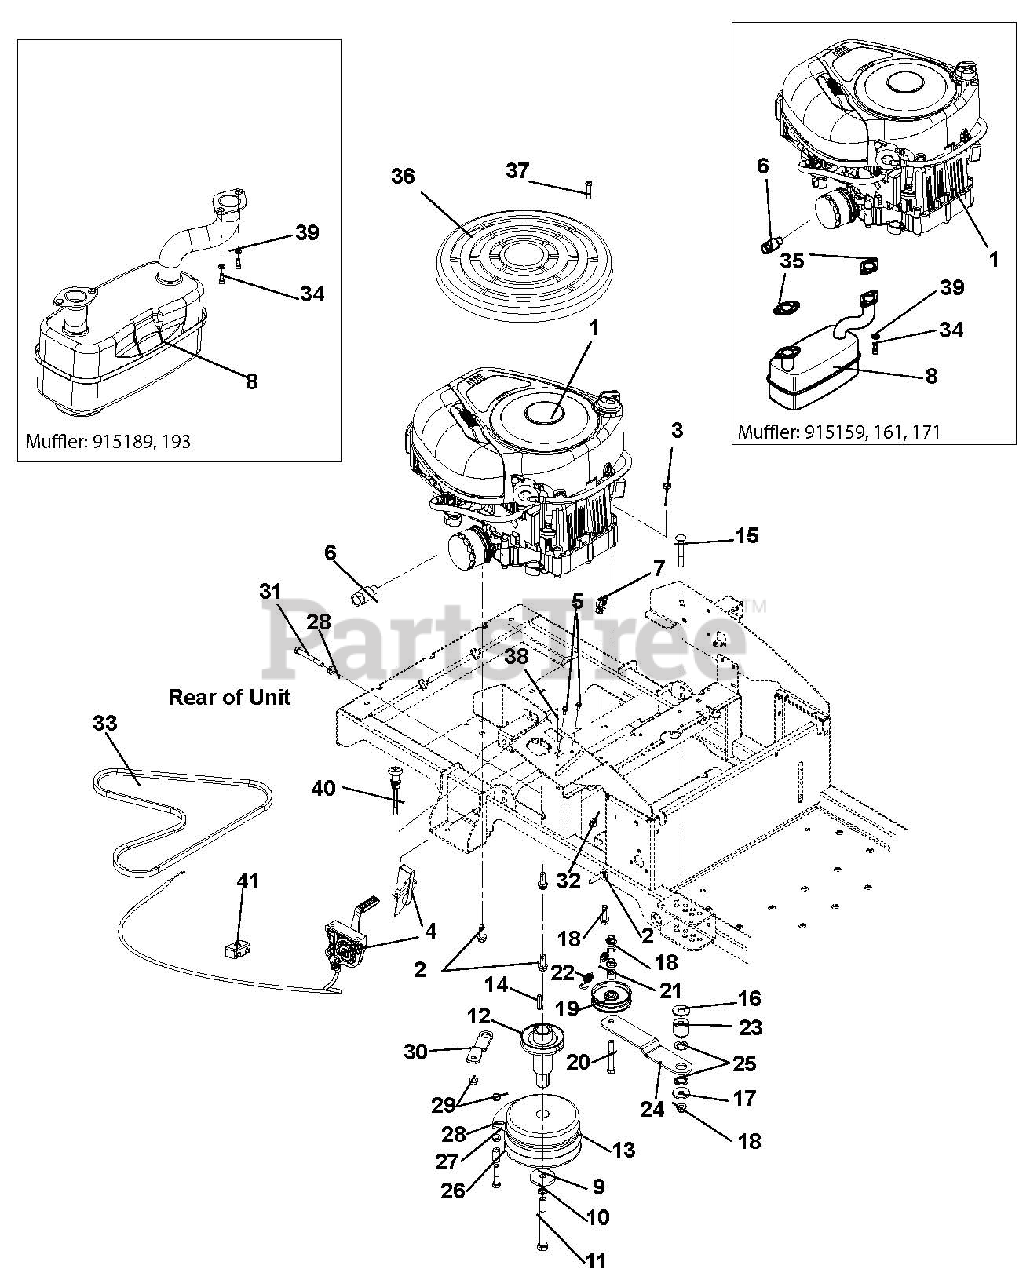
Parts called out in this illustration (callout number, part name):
1	ENGINE, KOHLER TWIN 20 HP
1	ENGINE, KOHLER TWIN - 22HP
1	ENGINE, B&S 16 HP TWIN
2	@SCR-TAP .38-16X1.25 HWH TR YZ
3	@NUT-LK-CTR-JAM .375-16 YWZC
4	CABLE, THROTTLE
4	CABLE, THROTTLE/CHOKE
5	@SCR-TAP 10-24X.50 HWH TR YWZC
6	DRAIN, OIL
7	WIRE CLIP
8	MUFFLER, KOHLER TWIN
8	MUFFLER - TWIN BRIGGS
9	WSHR-FL-STL .469X2.00X.25 YWZC
10	@WSHR-LK .44X.109 REG YWZC
11	BLT-HEX .44-20X4.50 GR8 YWZC
12	WMT-PTO EXTENSION W/SHEAVE
13	CLUTCH, 105 FT*LB MONO POLE
14	KEY-SQ .25 X 1.25 X .25 SAE
15	@BLT-RDHDSQNK .38-16X2.75 G5YZ
16	@WSHR-FL-STL.563X1.38X.109YWZC
17	WSHR-FL-STL .406X1.375X.135 YZ
18	@NUT-LK-NYL-FLG .38-16 YWZC
19	PULLEY, ENGINE CLUTCH 03608
20	@BLT-HEX .38-16X2.75 GR5 YWZC
21	BSHG-SLV .391X.688X.52 PM
22	SPRING, EXTENSION
23	SPACER, GROUND DRIVE IDLER
24	IDLER ARM, GROUND DRIVE
25	BUSHING, IDLER ARM
26	SCR-CAP .31-18X1 3/4 S/HD YWZC
27	SPACER, RUBBER 5/16 IDX1.0 LG
28	@NUT-SPNLK-FLG .312-18 YWZC
29	@NUT-LK-TOP-FLG .31-18 YWZC
30	BRKT, CLUTCH STOP
31	@BLT-HEX .31-18X2.75 GR5 YWZC
32	@NUT-LK-NYL-FLG .31-18 YWZC
33	V-BELT, HA-RAW EDGE
34	SCR-CAP .31-18X.75 S/HD
35	GASKET, MUFFLER COURAGE TWIN
36	GUARD, BRIGGS ENGINE
37	SCREW, 8-16X.87 PHPAN 3 LOBE
38	PLUG, 5/8" SQ BLACK (14-20GA)
39	@WSHR-LK .31X.078 REG YWZC
40	CABLE, CHOKE (SNAP IN)
41	CLIP, ENGINE CABLE
